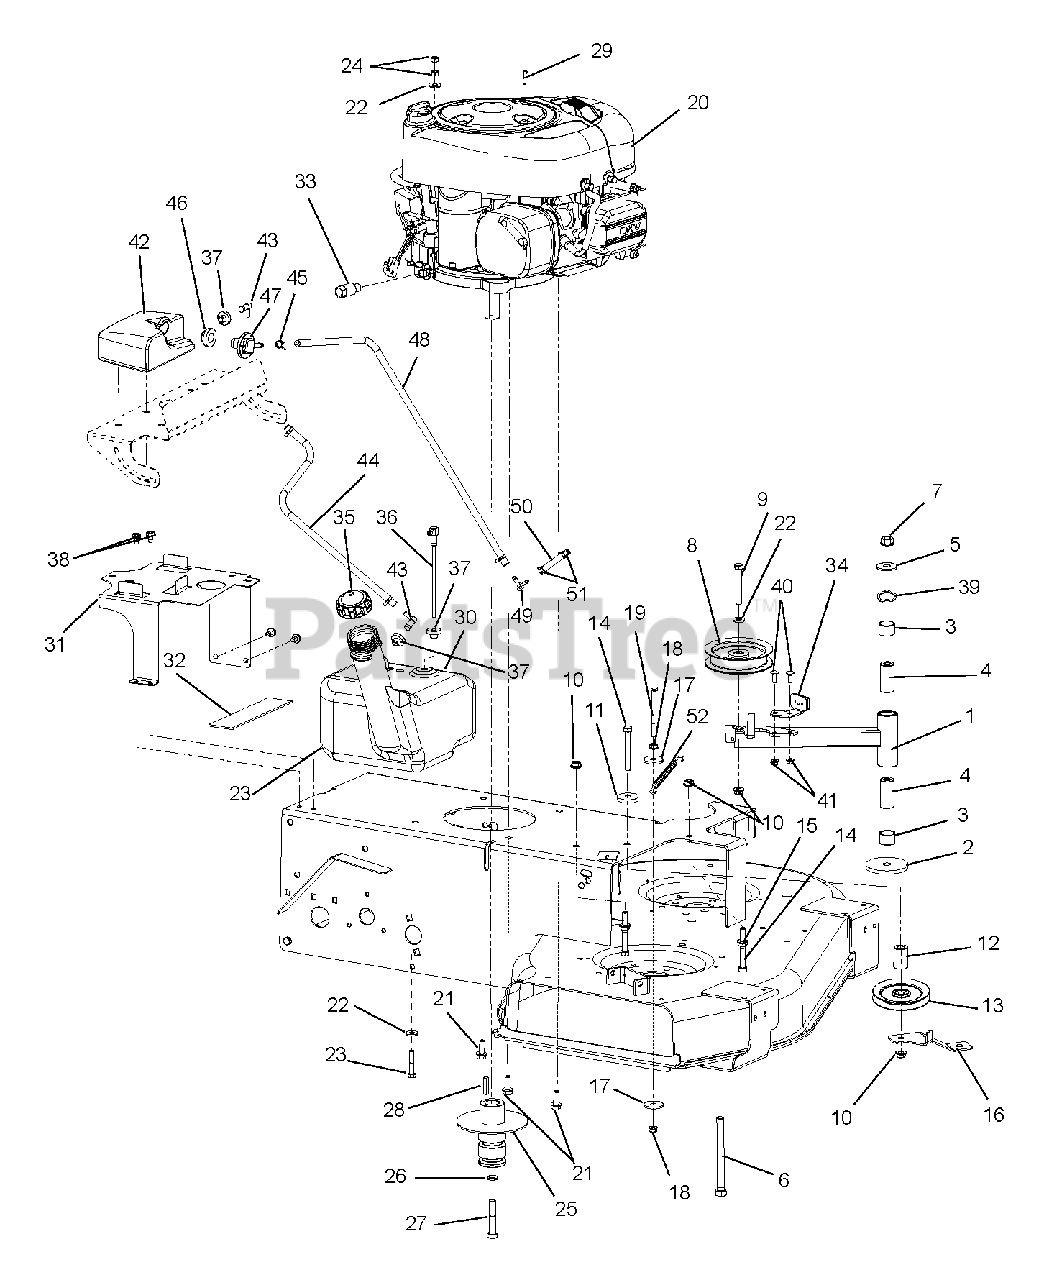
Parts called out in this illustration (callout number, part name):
1	Weldment, PTO Idler Arm
2	Washer, Flat .531 x 3.00 x .25
3	Bearing 1.00 x 1.12 x .75
4	Bushing, Spacer .505/.500 x .999/.996 x 2.05/2.03
5	Washer, Flat Steel .511 x 1.44 x .125
6	Bolt, Hex .50-13 x 5.50
7	Nut, Locking Top Flange .50-13
8	Idler, Flat .38 x 4.00 x 1.06
9	Bolt, Hex .38-16 x 2.75
10	Nut, Locking Top Flange .38-16
11	Washer, Flat Steel .406 x 1.50 x .245
12	Spacer, .437 x 1.00 x 1.23
13	Idler, 4.00 x .38
14	Bolt, Hex .38-16 x 3.00
15	Nut, Flange .375-16
16	Bracket, Idler Brace
17	Washer, Flat Steel .406 x 1.375 x .135
18	Nut, Spin-Lock Flange .312-18
19	Bolt, Hex .31-18 x 3.50
20	Engine, Briggs & Stratton, 14.5Hp
21	Screw, Hex Washer Head Tapping .38-16 x 1.00 (Torque = 374 – 562 lbf-in (42.26 – 63.5 Nm))
22	Washer, Flat Steel .38 x .875 x .083
23	Bolt, Hex .31-18 x 1.75
24	Nut, Locking Center .31-18
25	Pulley, Deck Drive
26	Washer, Locking .44 x .109
27	Bolt, Hex .44-20 x 2.50 (Torque = 394 – 590 lbf-in (44.52 – 66.66 Nm))
28	Key, Square .25 x 1.25 x .25
30	Tank, Fuel
31	Bracket, Gas Tank Mount
32	Pad, Gas Tank
33	Drain, Oil
34	Assembly, Brake Pad
35	Fuel Cap
36	Assembly, Pickup, Fuel 6.5L
37	Bushing, Flange .375 x 1.062 x .625
38	Screw, Tapping .31-18 x .50 Hex Washer Head
39	Washer, Wave 1.09 x 1.37 x .016
40	Bolt, Round Head Square Neck .25-20 x .75 Grade 5
41	Nut, Locking-Top-Flange .25-20
42	Tank, Fuel Expansion
43	Fitting, Straight Fuel Plastic
44	Fuel Line
45	Hose Clamp
46	Grommet, Remote Vent
47	Vent, Roll-Over
48	Fuel Line
50	3/16 ID Fuel Line
51	Hose Clamps
52	Spring, Engine
